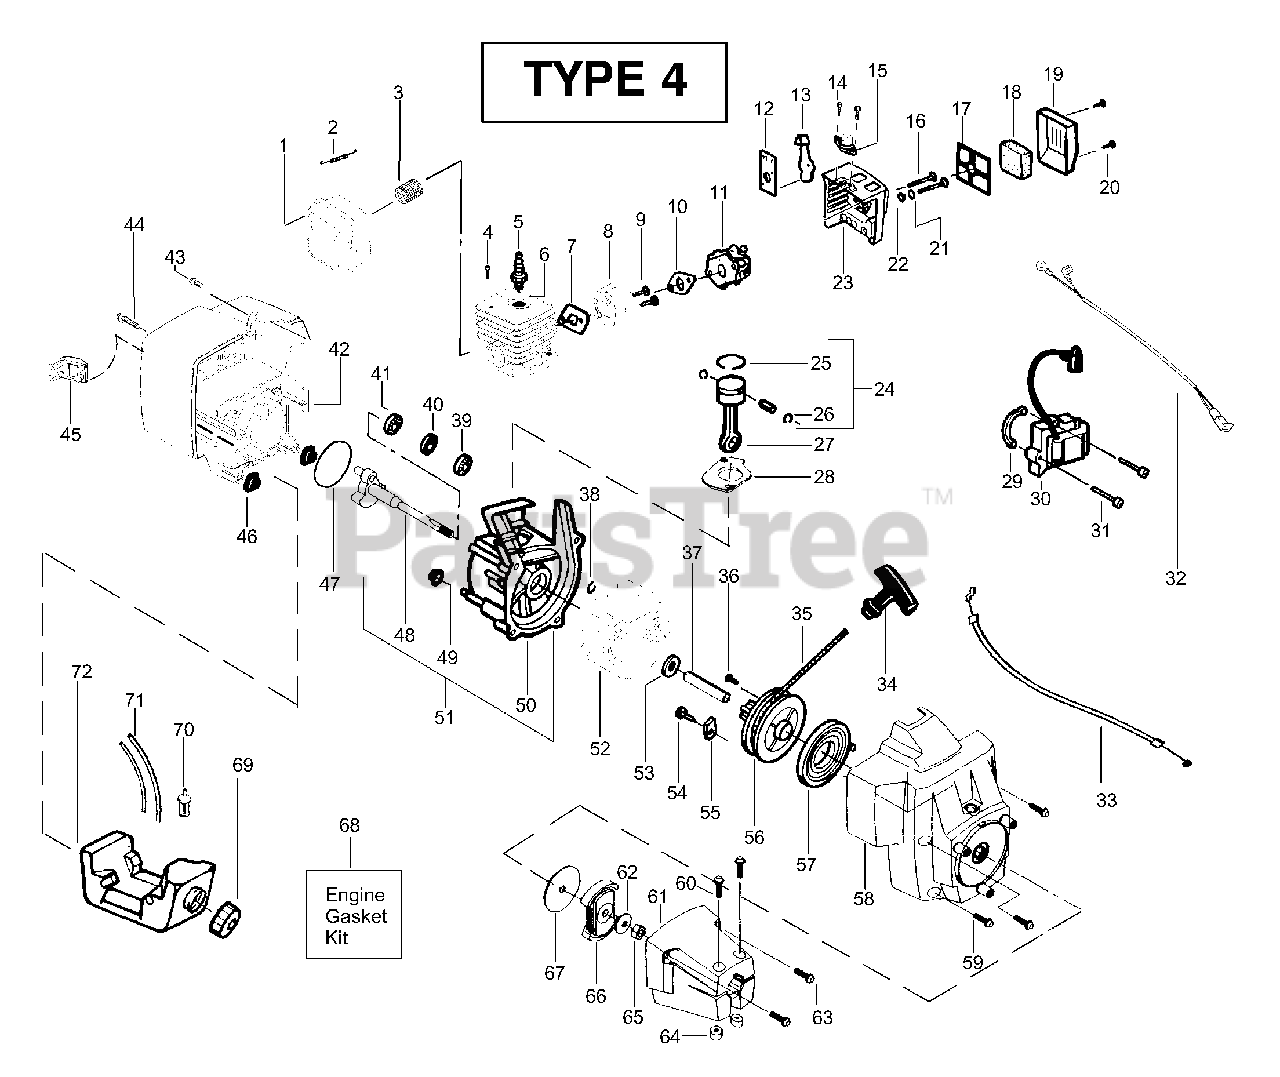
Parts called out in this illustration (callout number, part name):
1	Kit - Muffler
2	Spring-Muffler
3	Kit-Spark Arrestor
4	Screw-Cylinder
5	Spark Plug (RCJ-6Y)
6	Kit - Cylinder
7	Gasket-Cyl./Carb. (kit)
8	Adapter-Carb.
10	Gasket-Carb. (kit)
11	Kit - Carb. WT-380
12	Choke Plate Mounting
13	Shutter-Choke
14	Screw-Air Purge
15	Assy-Air Purge
17	Plate - Filter Support
18	Foam-Air Filter
19	Cover-Air Box
21	Spacer-Choke
23	Box-Air Filter
24	Kit - Piston
25	Piston Ring
26	Retainer-Piston Pin
27	Kit-Connecting Rod Assy
28	Gasket-Cylinder (kit)
29	Spacer-Module
30	Ignition Module
32	Assy-Switch Wire
33	Assy-Throttle Cable
34	Handle-Starter
35	Kit - Rope
37	Spacer-Flywheel
38	Retain. Ring-C'shaft
39	Outer Bearing
40	Kit-C'case Seal
41	Inner Bearing
42	Shroud-Rear
44	Screw
45	Guard-Muffler
46	Isolator-Shroud
47	O-Ring-C'case/Shrd (kit)
48	Assy-Crankshaft
49	Isolator-Crankcase
50	Assy-Crankcase
51	Assy-C'case & C'shaft
52	Assy-Flywheel
55	Retainer
56	Kit-Starter Pull
57	Spring-Starter
58	Assy.-Fan Hsg
59	Screw
61	Assy-Clutch Hsg.
62	Washer-Flat
65	Nut-Clutch
66	Assy-Clutch
67	Washer-Clutch
68	Kit-Engine Gasket
69	Assy-Fuel Cap
70	Assy-Fuel Pickup
71	Kit-Fuel Line
72	Assy-Fuel Tank
